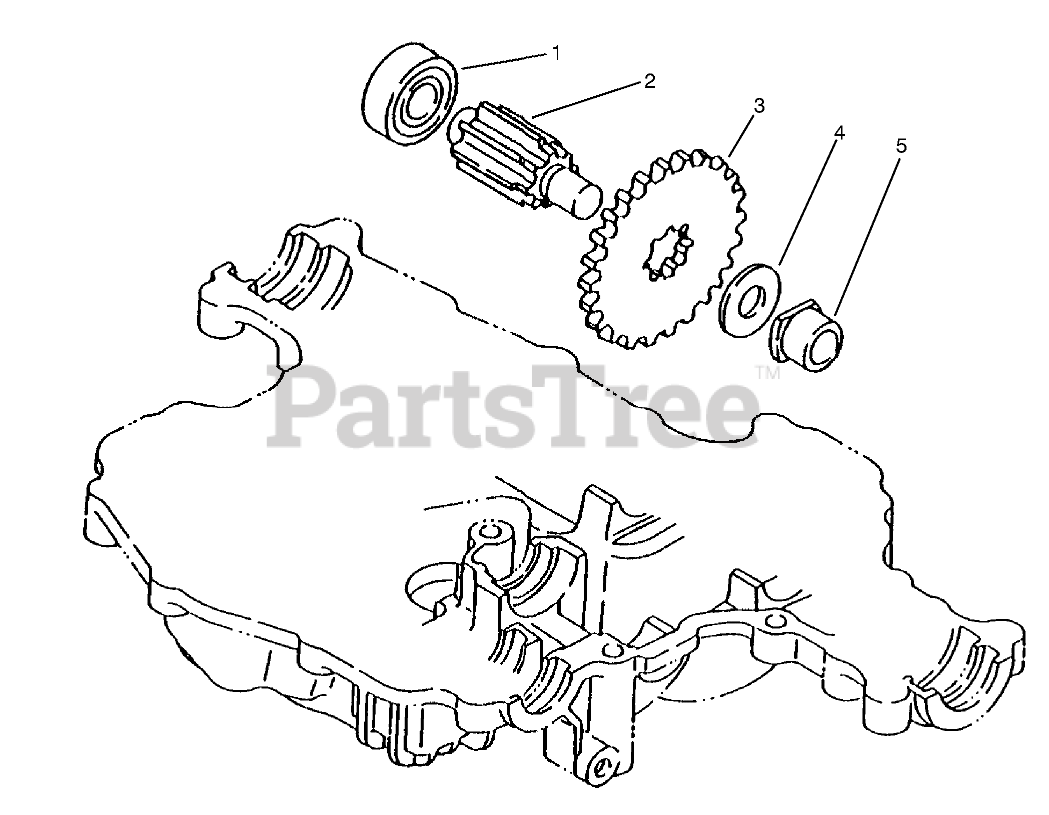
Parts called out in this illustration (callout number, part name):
1	BEARING
2	SHAFT - FINAL PINION
3	GEAR-FINAL SHAFT
4	WASHER
5	BUSHING
